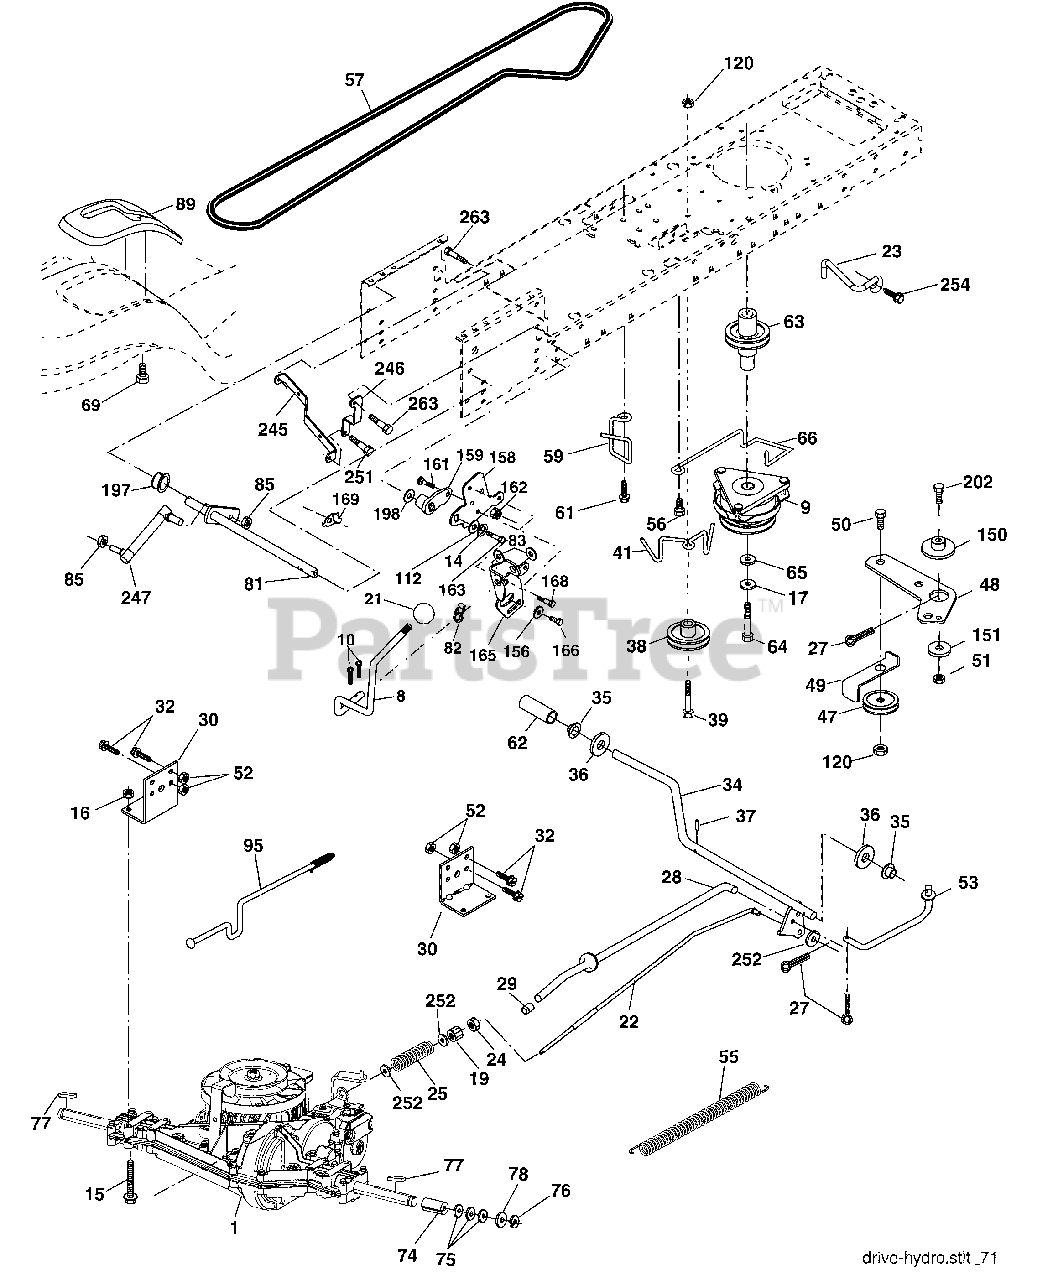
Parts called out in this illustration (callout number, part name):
8	Rod Shift Fender
9	Clutch Electric
10	Pin Cotter 1/8 x 1 CAD
14	Washer Lock Hvy Helical
15	Bolt Hex Flghd 5/16-18 Gr. 5
16	Nut Lock Hex W/Ins. 5/16-18 unc
17	Washer 1-1/2 OD x 15/32 ID x .250
19	Nut Lock Hex W/Wsh 3/8-16 unc
22	Rod, Brake Hydro
23	Bracket Anti-Rot
24	Locknut
25	Spring, Brake Rod
27	Pin Cotter 1/8 x 3/4 CAD.
28	Rod, Parking Brake
29	Cap, Parking Brake
30	Bracket, Transaxle
32	Bolt Hex Hd 5/16-18 unc x 3/4
34	Shaft, Foot Pedal Nibbed
35	Bearing, Nylon
37	Pin, Roll
38	Pulley, Idler, Flat Composite
39	Bolt 3/8-16 x 2-3/4 Gr. 5
41	Keeper, Belt Idler Fool-Proof
47	Pulley, Idler, V-Groove
48	Bellcrank Clutch Grnd Drv Stl
49	Retainer, Belt
50	Bolt Carr. SH 3/8-16 x 1-1/2 Gr. 5
52	Nut Crown Lock 5/16-18
53	Link, Clutch
55	Spring, Return, Clutch
56	Screw 3/8-16 x 1-1/4
57	V-Belt, Ground Drive
59	Keeper, Center Span
61	Screw 3/8-16 x .875
62	Cover, Pedal
63	Pulley, Engine
64	Bolt Hex 7/16-20 x 4 x Gr. 5
65	Washer
66	Keeper Belt Engine Hydro
69	Screw Hex Wsh Hi-Lo 1/4-1/2 unc
74	Spacer, Axle
75	Washer 25/32 x 1-1/4 x 16 Ga.
77	Key, Square
78	Washer 25/32 x 1-5/8 x 16 Ga.
81	Shaft Asm. Cross
82	Spring Torsion T/A
83	Washer 17/32 x 3/4 x 16 Ga.
85	Nut Lock Center 1/4-28
89	Console, Shift
95	Control Asm. Bypass Disconnect
112	Washer 9/32 x 3/4 x 10 Ga.
120	Nut Lock 3/8-16
150	Spacer Retainer
151	Washer 13/32 x 2 x 10 Ga.
156	Washer Srrted 5/16 ID x 1.125
158	Bracket Shift Mount
159	Hub Shift
161	Bolt Rdhd Sqnk 1/4-20 x 3/4 Gr. 5
162	Nut Crownlock 1/4-20 unc
163	Bolt Hex Fin 1/4-20 unc x 1 Gr. 5
165	Bracket Pivot Lever
166	Screw 5/16-18 x 5/8
168	Bolt Shoulder 5/16-18 x .561
169	Plate Fastening Lt\
197	Nyliner Snap-In 5/8" ID
198	Washer Nyliner 7/8 ID x .105
202	Bolt 3/8-16 x 1-3/4 Gr. 5
245	Strap Torque Lh
246	Strap Torque Rh
247	Link Shift Transaxle
251	Screw 5/16-18 x 1
252	Washer
254	Screw 3/8-16 x 1
263	Screw Hexwsh Thdr 3/8-16 x 3/4
